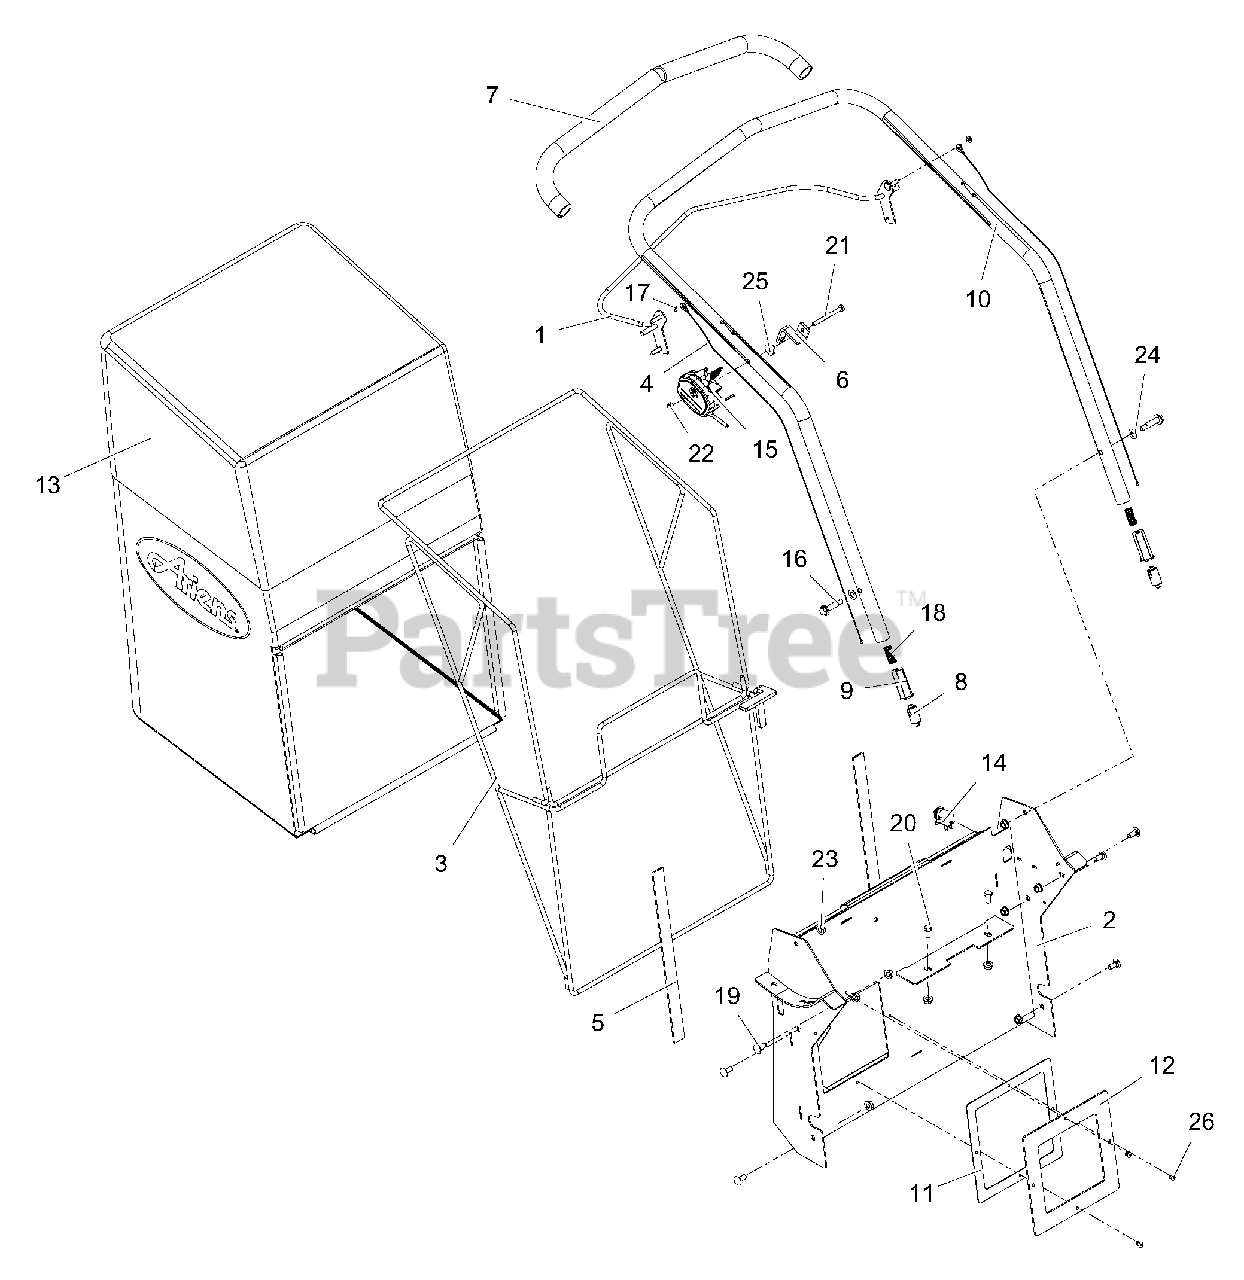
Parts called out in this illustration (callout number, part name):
1	WLDMT, BAIL - APV TRACTION
2	WLDMT, BAG BACKING PLATE
3	WLDMT, BAG FRAME - APV
4	CABLE, APV HANDLE ADJUST
5	TAPE-FOAM .12X1.00 VINYL
6	ANCHOR, CABLE
7	GRIP-HANDLEBAR, UPPER
8	PLUNGER, HANDLEBAR LOCKING
9	INSERT, HANDLEBAR ADJUST
10	HANDLEBAR - APV, UPPER
11	PLATE, SEAL BACKER
12	SEAL, RUBBER
13	BAG-APV ARIENS FELT
14	SWITCH- SNAP MTG N.C. W/BOOT
15	CABLE-ENG, THROTTLE/CHOKE 37.2
16	BLT-SHLDR, .50X1.15X.312-18GR5
17	NUT-PUSH .25X.50 O.D.
18	SPRING, COMPRESSION
19	@BLT-RDHDSQNK .31-18X.75 G5YZ
20	BLT-HEX .31-18X.63 GR5 YWZC
21	@BLT-HEX .25-20X2.75 GR5 YWZC
22	@NUT-LK-CTR .25-20 YWZC
23	@NUT-LK-TOP-FLG .31-18 YWZC
24	WSHR,.385X.745X.030 STL YWZC
25	WSHR-FL-STL .328X.87X.179 YWZC
26	RVT-POP .187 YZ
